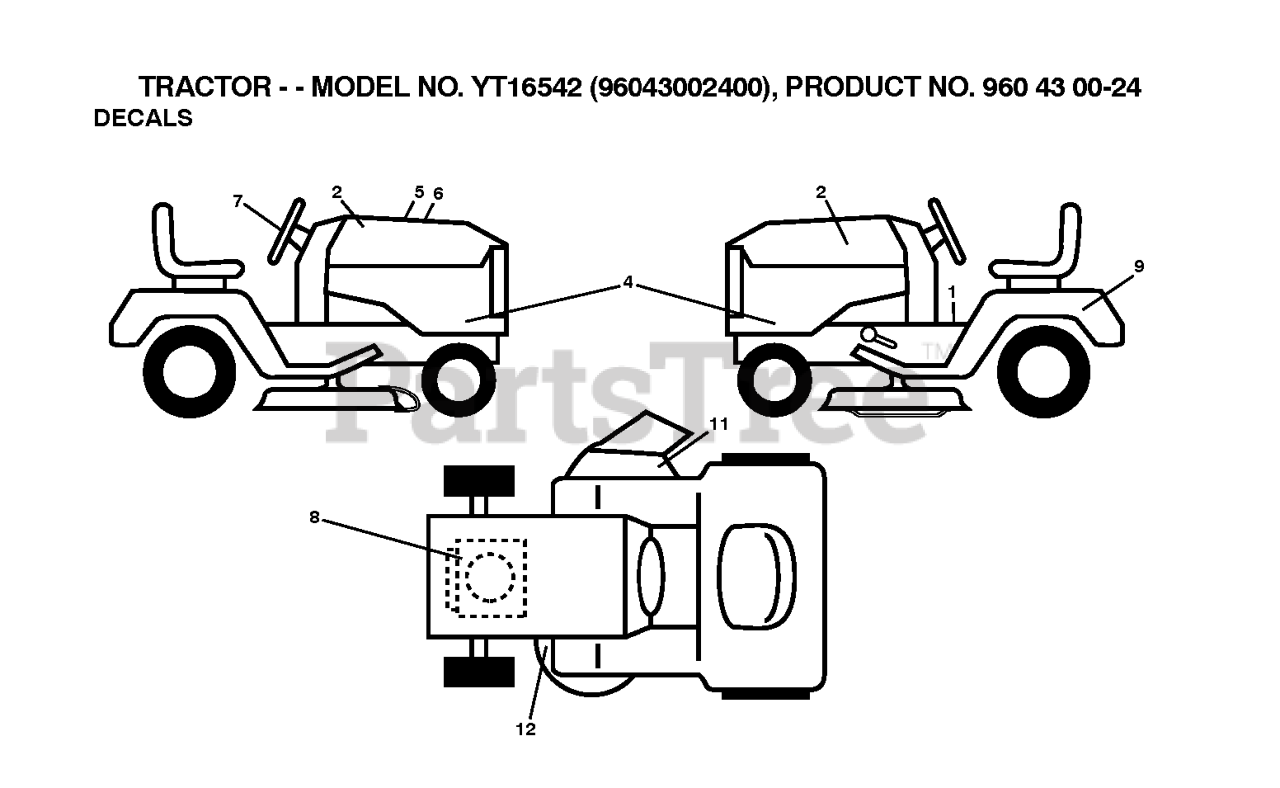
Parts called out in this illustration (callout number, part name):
1	DECAL,OPERATORS
2	DECAL.HOOD.NAMELOGO.HUSQ
4	Decal, Hood Panel
5	DECAL HOOD CUST. RESP.
6	Decal, Replacement
7	DECAL.WHEEL.STRG.LGN.H
8	Decal, Replacement
9	DECAL BTRY SYMBOLS
11	DECAL.WARN.KEEP.HAND.AWAY
12	DECAL V BELT SCHEMATIC
